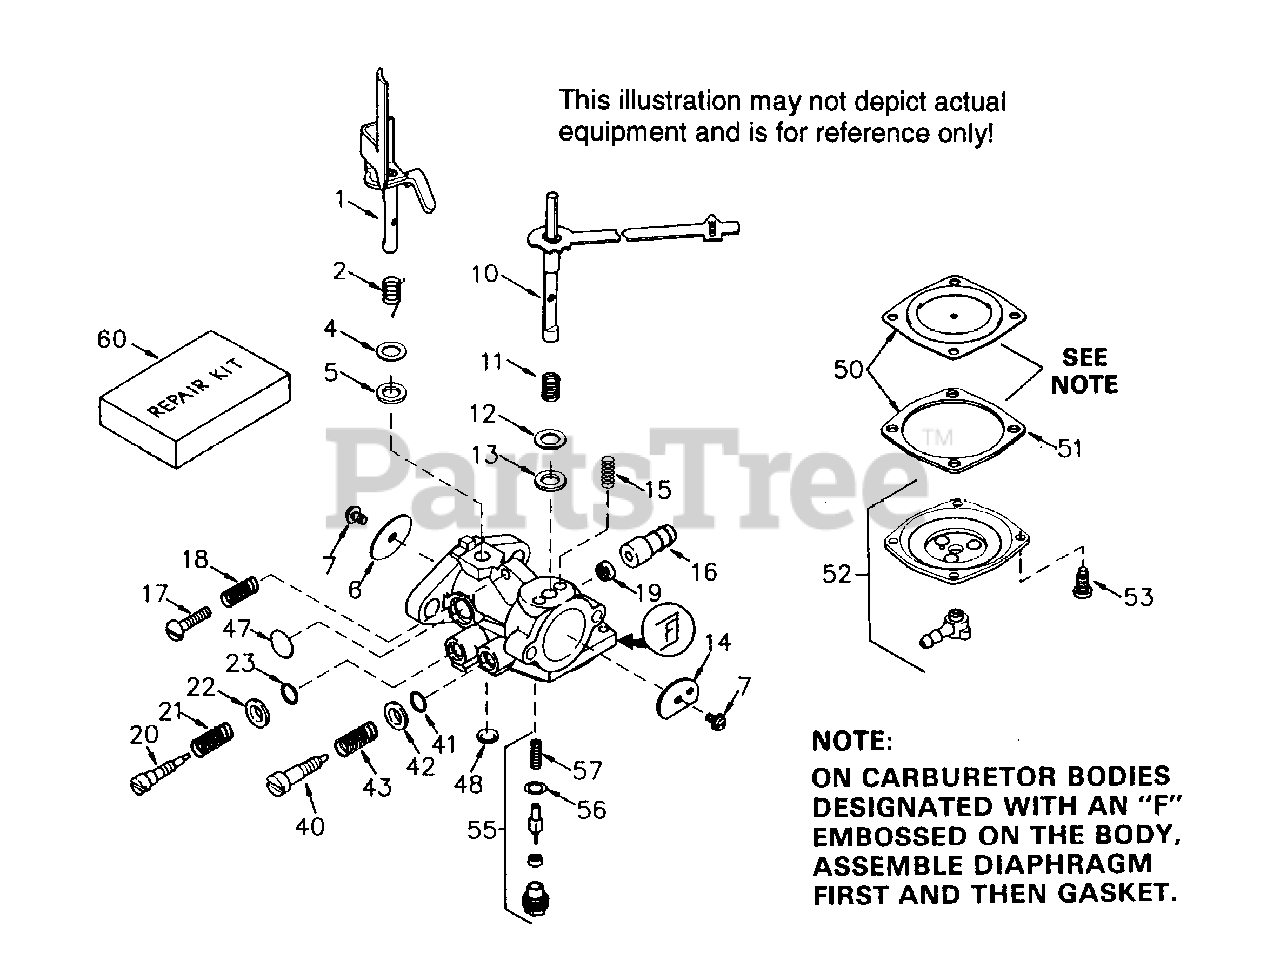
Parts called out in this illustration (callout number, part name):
1	Throttle Shaft & Lever Assembly
2	Throttle Return Spring
6	Throttle Shutter
7	Throttle & Choke Shutter Screw
10	Choke Shaft & Lever Assembly
16	Fuel Fitting
17	Idle Speed Screw
18	Tension Spring
20	Idle Mixture Screw
21	Idle Tension Spring
22	Idle Screw Washer
23	* Idle Screw "O" Ring
40	Main Adjustment Screw
41	* Main Adjustment Screw "O" Ring
42	Main Adjustment Screw Washer
43	Main Adjustment Screw Tension Spring
47	* Welch Plug, Idle Mixing Well
48	* Welch Plug
50	* Diaphragm & Gasket Assy. (Incl. 51)
51	* Cover Gasket
53	Cover Screw
55	* Inlet Needle & Seat Kit Incl. 56 & 57
56	* Inlet Washer
57	* Inlet Spring
60	Repair Kit (Incl. items marked PK in notes) Incl. (1) each of part #'s6307 42, 630748, 630750A, 630932A,630953, 630978, 631049, 631190,630740 (2), 63 0746 (3)
